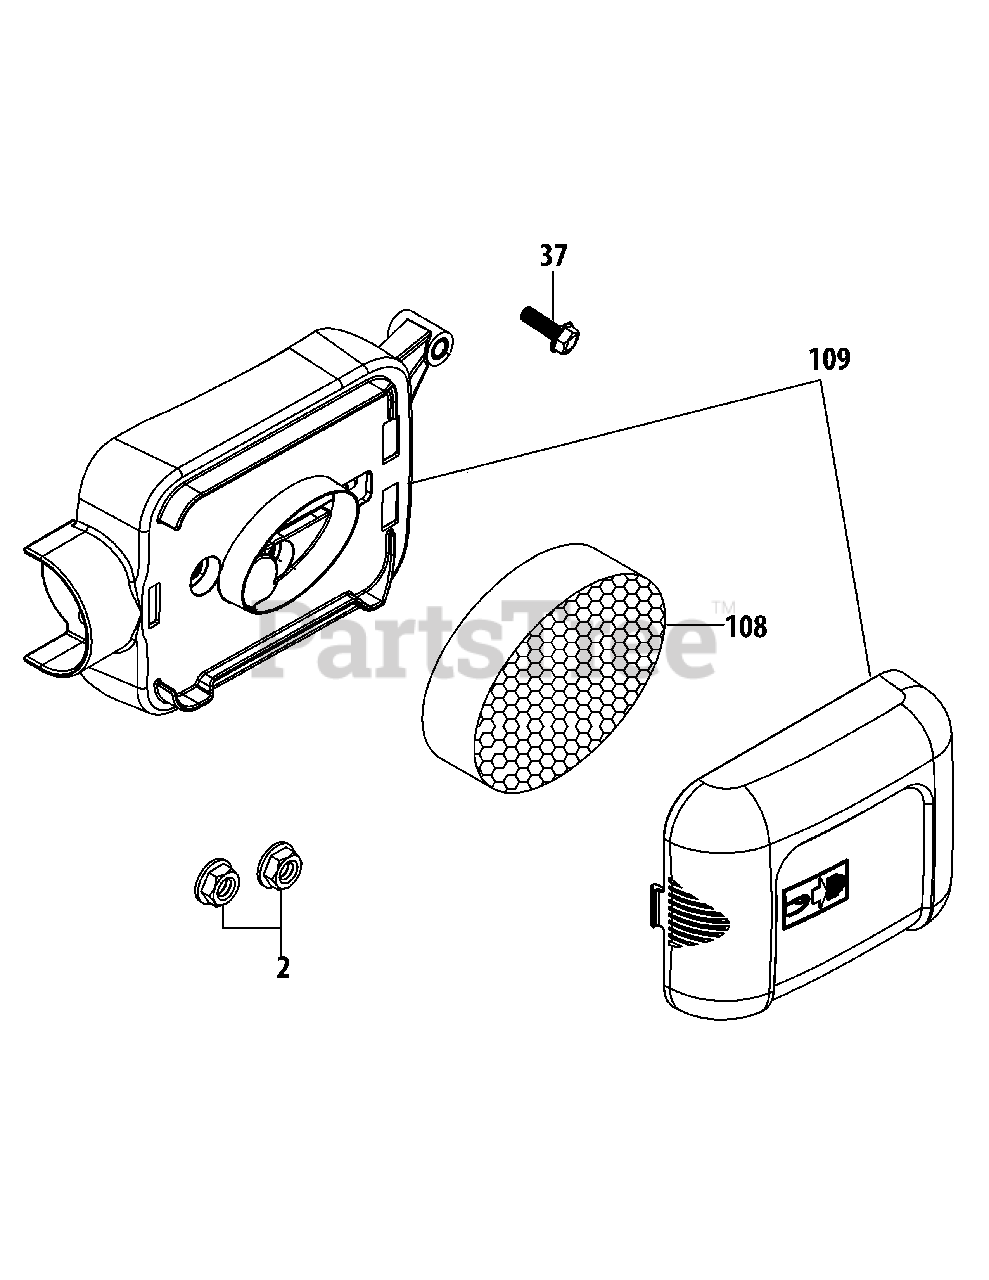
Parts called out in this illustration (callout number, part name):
2	Nut M6X10M
37	Bolt M6X30
108	Air Filter Element, Oval
109	Air Cleaner Housing Assy
